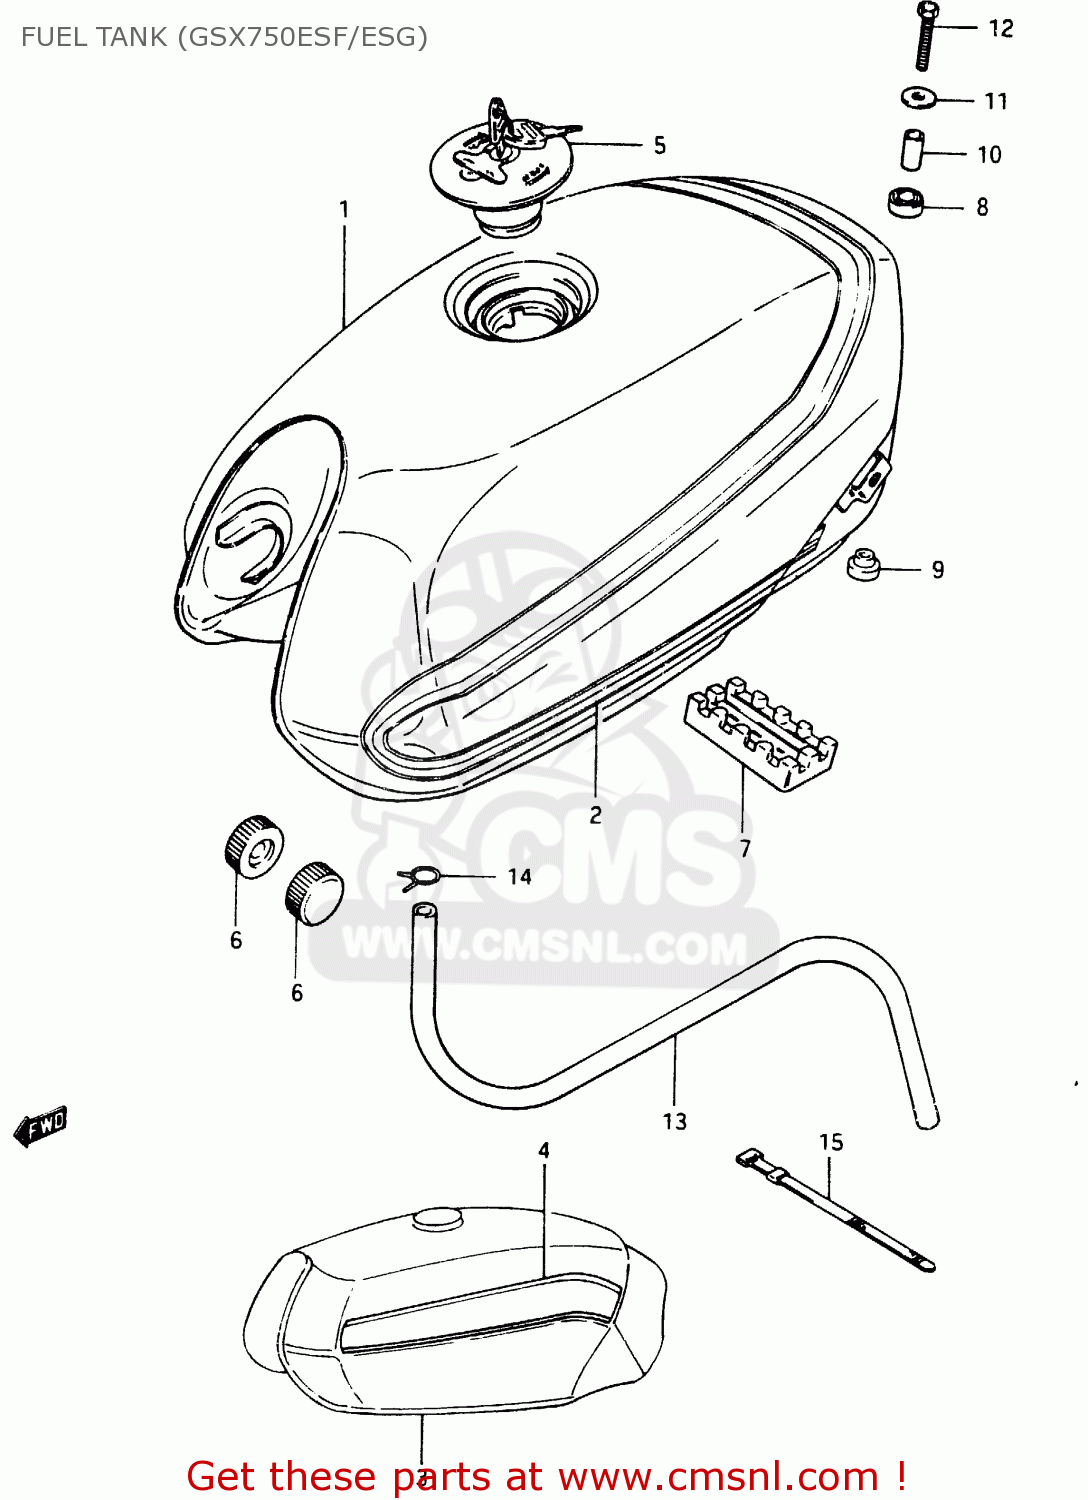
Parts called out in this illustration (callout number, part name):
1	TANK, FUEL
2	TAPE SET, FUEL TANK
3	TANK ASSY, FUEL
4	TAPE SET, FUEL TANK
5	CAP, FILLER
6	CUSHION
7	CUSHION,FUEL TANK CTR
8	CUSHION
9	CUSHION
10	SPACER
11	WASHER (6.5X24X1.6)
12	BOLT
13	HOSE,FUEL
14	CLIP
15	CLIP(ID:16)
